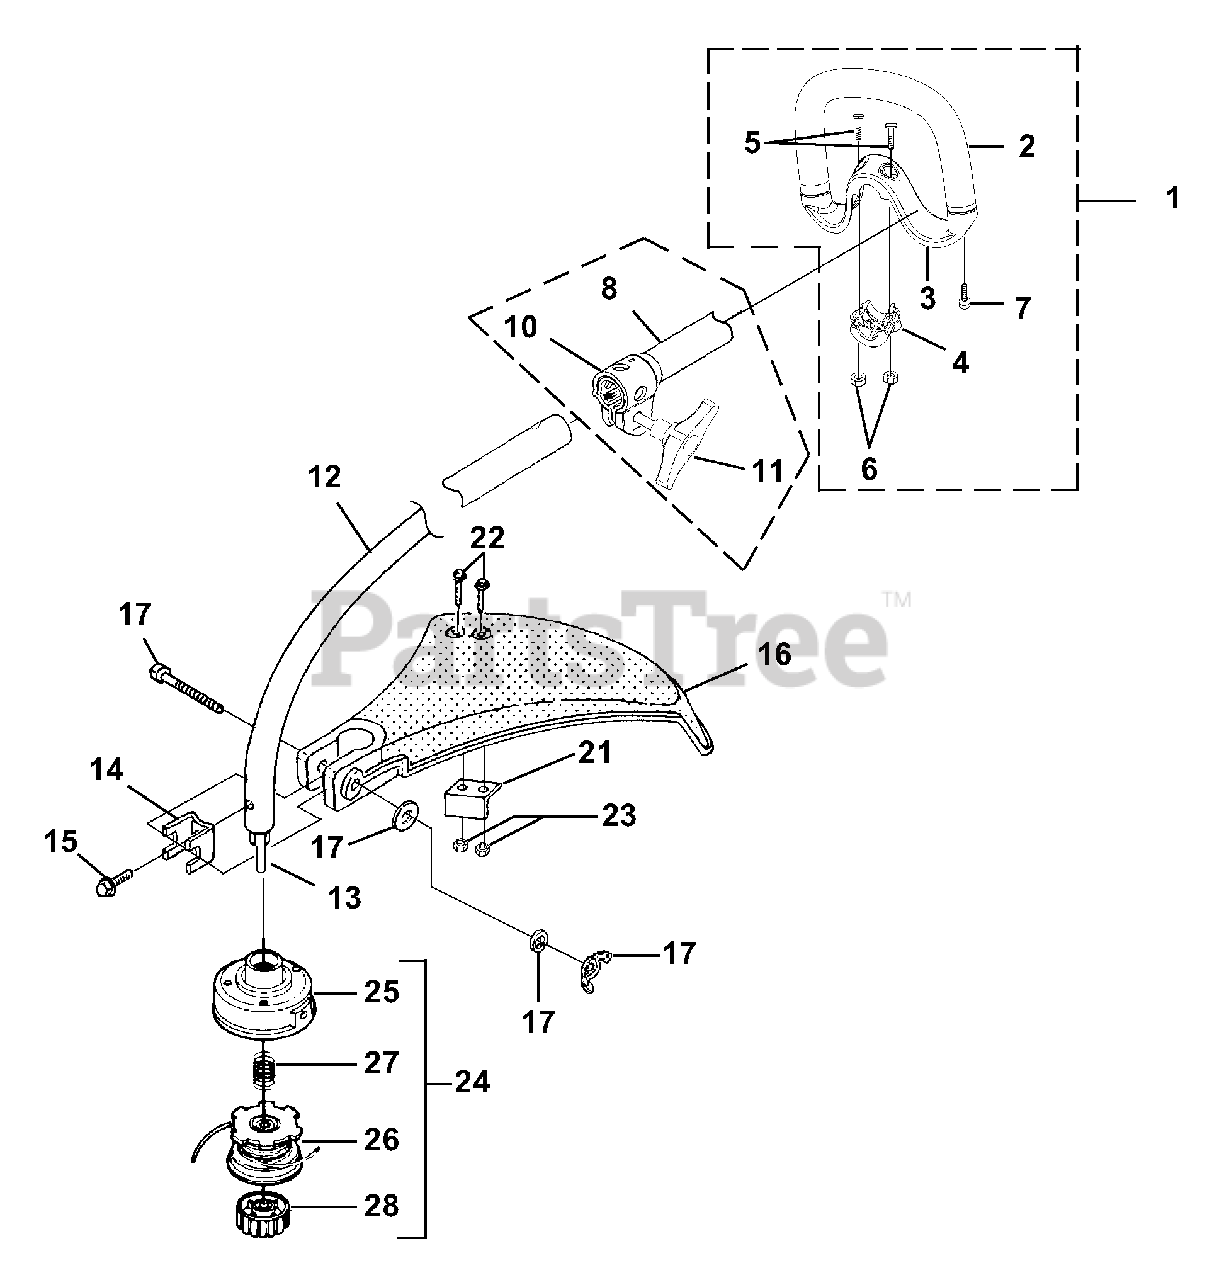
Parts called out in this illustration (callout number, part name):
1	HANDLE-Complete
2	HANDLE W/Grip
3	CLAMP - "M"
4	CLAMP-Assist Handle
8	DRIVESHAFT ASSY. (Upper)
10	COUPLER ASSEMBLY
12	DRIVESHAFT HOUSING (Lower)
13	SHAFT-Flex
14	CLAMP
15	SCREW-Sems Hex (10-24 X 3/8")
16	DEFLECTOR & BLADE KIT (55 Deg.)
17	SCREW-Cap Hex Hd. (1/4-20 X 2")
21	BLADE-Cut-Off
22	SCREW-Mech. Hex Hd. (10-24 X 7/8")
23	NUT-Hex (10-24)
24	STRINGHEAD-Complete (.095")
25	HOUSING & EYELET (Dual Line)
26	SPOOL & STRING (.095")
27	SPRING-Compression
28	RETAINER-Spool (R.H. Thread, Black)
